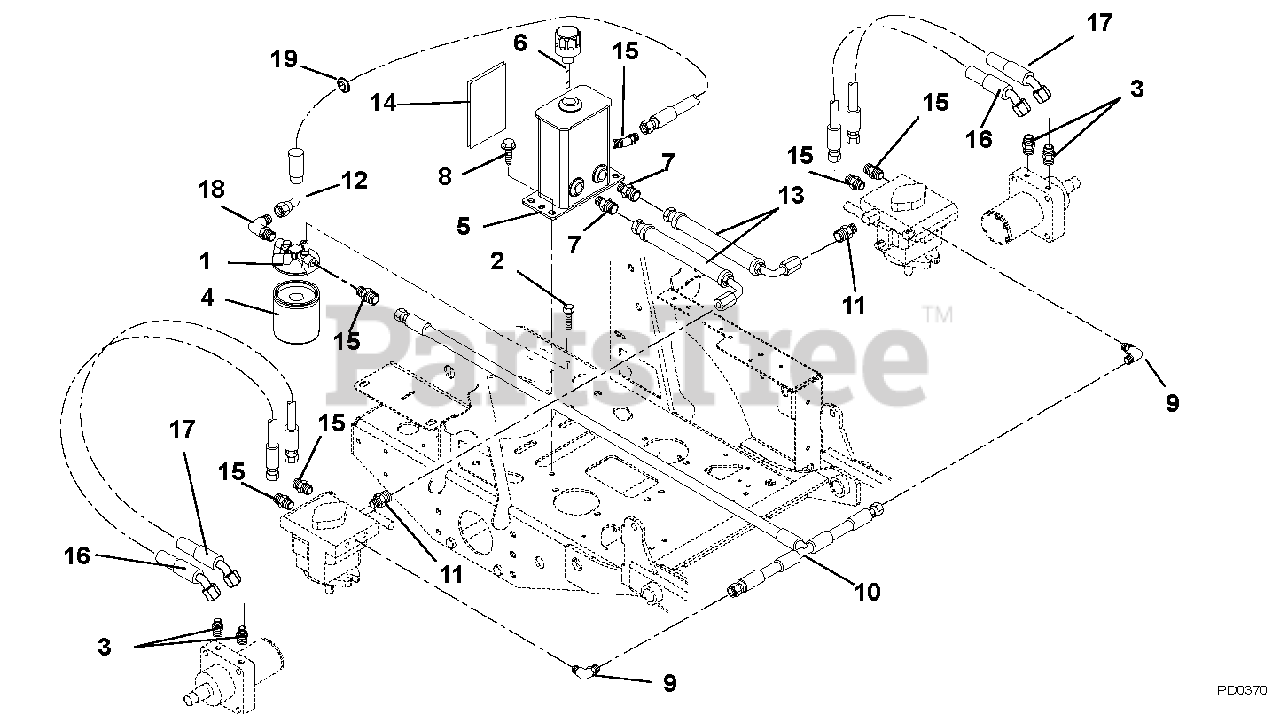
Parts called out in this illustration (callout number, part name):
1	Head, Filter
2	Bolt, Hex .25-20 x .50
3	Adapter, Hydraulic
4	Oil Filter
5	Weldment, Formed Hydraulic Tank - 3 Port
6	Breather Dipstick
7	Fitting, Hydraulic Straight M8O-M4F
8	Screw, Tapping .38-16 x .50 Hex Washer Head
9	Adapter, Hydraulic 8MB-12FPX90
10	Hose, Hydraulic .50 to .38 Tee Assembly
11	Fitting, Hydraulic (4-6 F5OLO)
12	Hose, Hydraulic .50-11-OK F8F0-F8F9
13	Hose, Hydraulic
14	Shield, Heat 5.50 x 4.50
15	Adapter, Face Seal 8 x 8 1/2 O-Ring 8 F5OLO, Steel
16	Hose, Hydraulic .50-11-3K
17	Hose, Hydraulic .50-12-3K
18	Fitting, Hydraulic EL M8F-M80
19	Grommet, 1.25ID x 1.50OD
